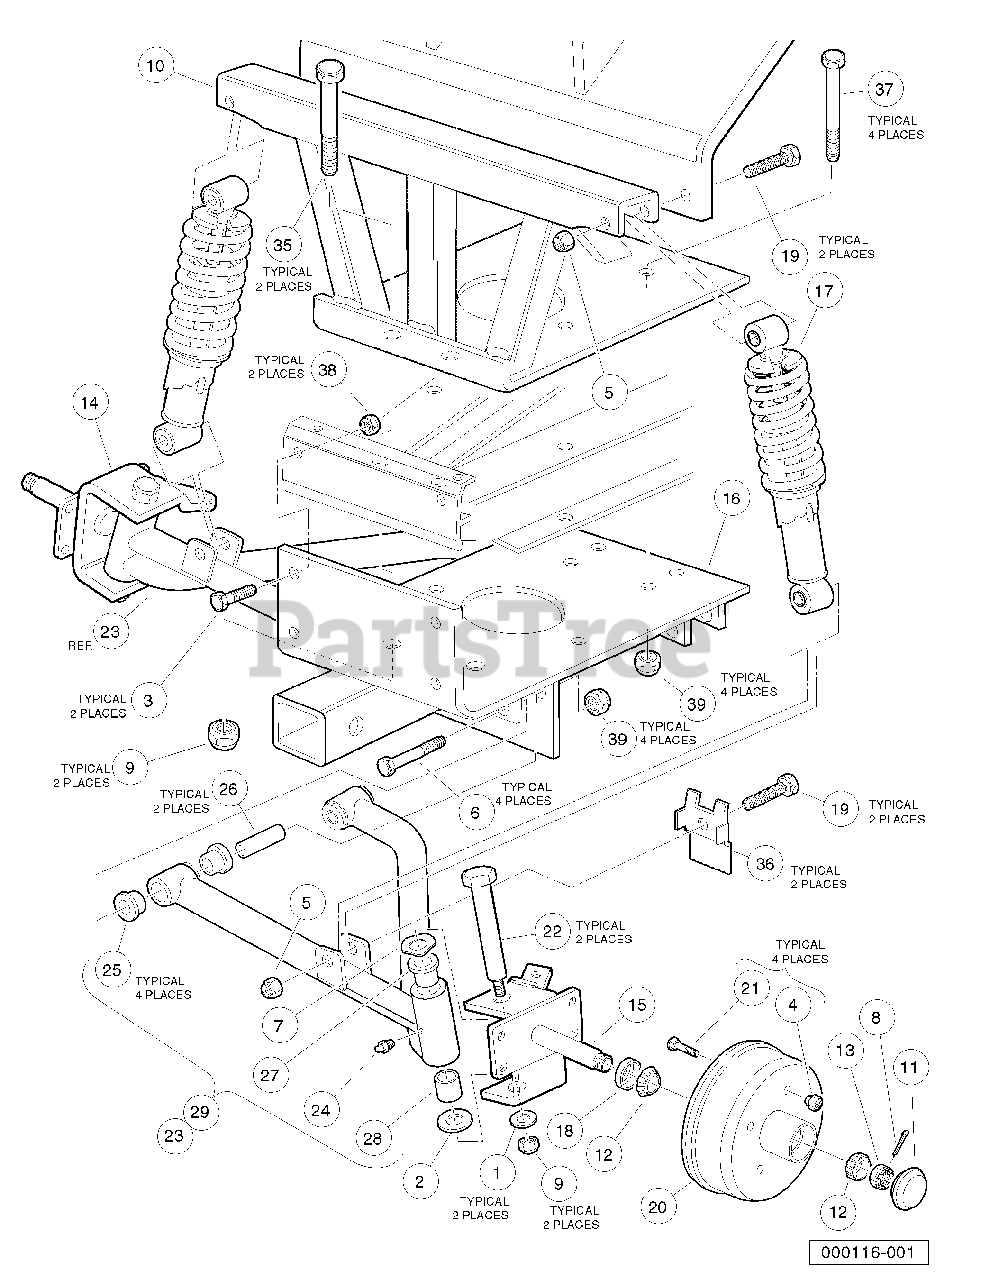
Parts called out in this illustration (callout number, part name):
1	Washer, 1/2 Type A Flat
2	Bearing, Thrust
3	Screw, 5/16-18 X 1.00 Hex Cap
4	.500-20 Unf Lug Nut
5	Locknut, 7/16-14 Nylon Insert
6	Screw, 3/8-16 X 2.75 Hx Hd Cap
7	Washer, 1.125 Od Wave
8	Pin, Cotter, 0.312 x 1.25
9	Locknut, 1/2-20 Nylon Insert
10	Shock Tower
11	Dust Cover
12	Bearing, Tapered
13	Nut, 1.00-14 Slotted Hex Jam
14	Assembly, Spindle, RH
15	Assembly, Spindle, LH
16	Suspension Mtg Plate
17	Shock Absorber, Coil Over
18	Seal, Dual-Lip
19	Screw, 7/16-14 X 2.50 Hex Cap
20	Assembly, Front Hub
22	King Pin Bolt Assembly
23	Right A-arm Asm
24	Fitting, 1/4-28 Thread-Forming Grease
25	Bushing, Urethane
26	Sleeve, A-Arm
27	Bushing, Flanged Bronze
28	Bushing, Bronze Spindle
29	Left A-Arm Asm
30	Fitting, 1/4-28 Thread-Forming Grease
31	Bushing, Urethane
32	Sleeve, A-Arm
33	Bushing, Flanged Bronze
34	Bushing, Bronze Spindle
35	Screw, 1/2-20 X 5.0 Hex Cap
36	Steering Stop Mtg Plate
37	Bolt, 3/8-16 X 4.50 Hex Head
38	Locknut, 5/16-18 Nylon Insert
39	Locknut, 3/8-16 Hex
